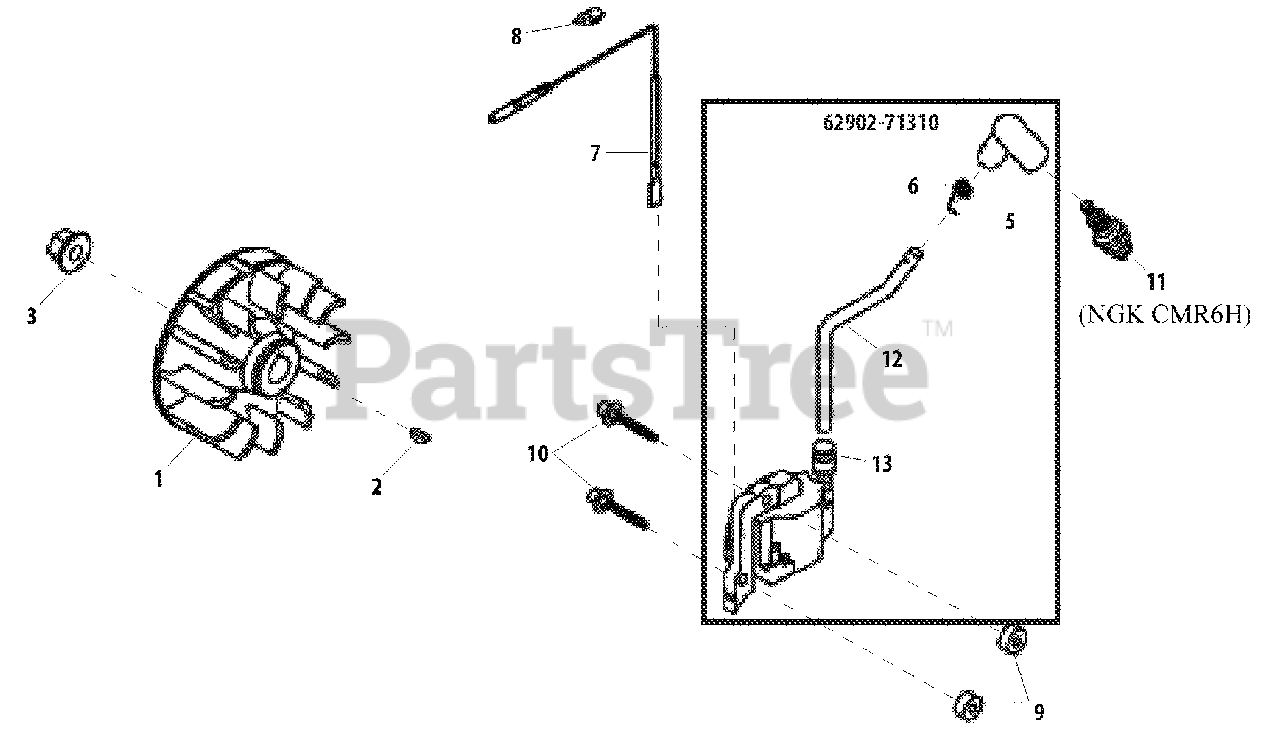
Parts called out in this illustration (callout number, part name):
1	FLYWHEEL
2	KEY - 3X10
3	NUT - 8
5	CAP, SPARK PLUG
6	TERMINAL, SPARK PLUG CAP
7	LEAD - IGNITION
8	GROMMET
9	INSULATOR
10	SCREW - 4X26
11	SPARK PLUG -- CMR-6H
13	GROMMET
62902-71310	IGNITION COIL ASSY
